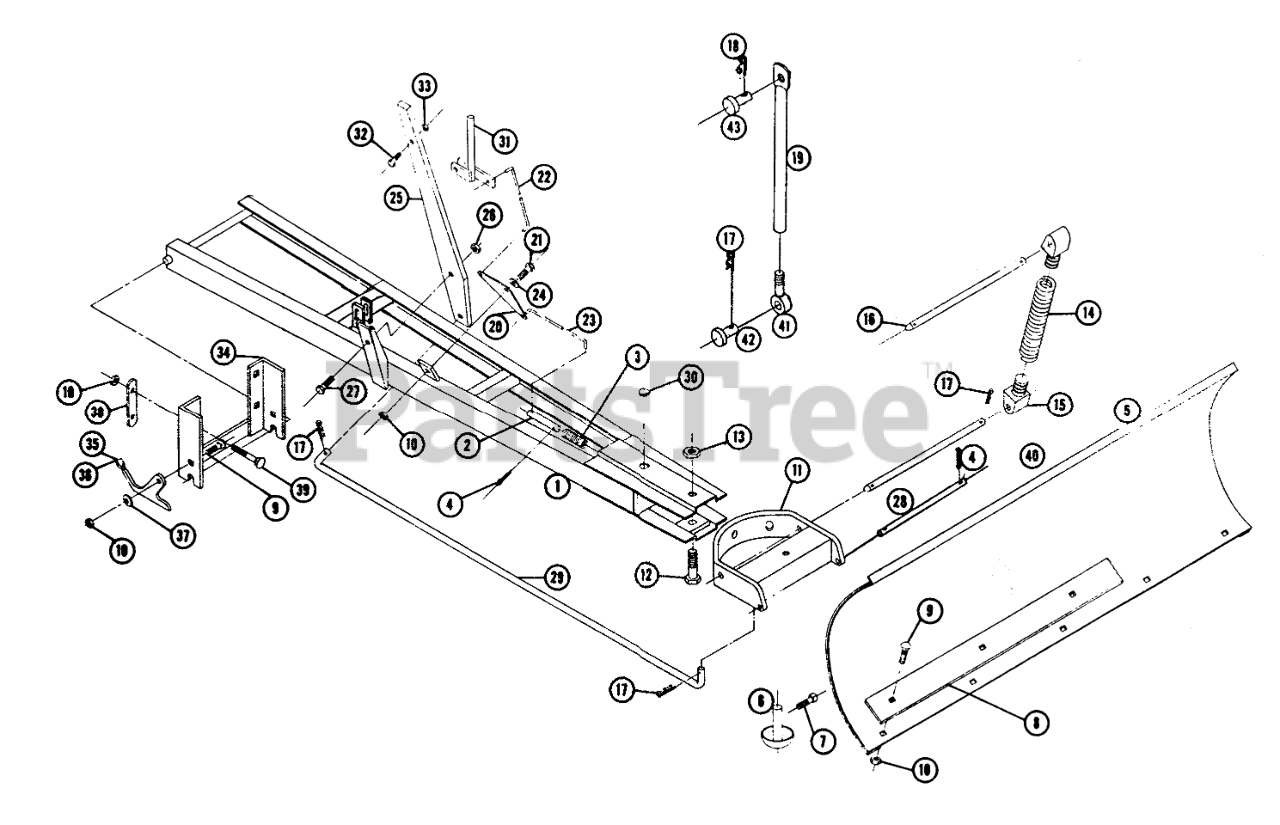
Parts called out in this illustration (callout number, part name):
1	Ass-y-Frame
2	Index Pin
3	SPRING-COMPRESSION
4	Cotter Pin
5	Ass-y-Blade
6	Skid
7	Set Screw 3/8-16 x 5/8 Sq. HD.
8	Plate-Blade Edge
9	Bolt 3/8-16 x 1
11	Sector and Channel
12	Bolt-Hex 3/4-16 x 3 3/4
13	Nut-Hex 3/4-16 Elastic Stop
14	Spring
15	Lug
16	ROD-PIVOT, BLADE
17	Hairpin
18	Hair Pin
19	Rod-Lift
20	Index Plate
21	Bolt-Hex 3/8-16 x 1
22	Rod-Upper Index
23	Head-Cylinder
24	Washer
25	Lever
26	Nut-1/2-13
27	Bolt Hex 1/2-13 x 1
28	ROD-LOWER
29	Rod-Blade Control
30	PLUG
31	INDEX LEVER
32	Bolt-Hex 1/4-20 x 1
33	Nut-Nylok
34	Ass-y Bracket-Mtg.
35	Plate-Latching R.H.
36	Plate-Latching L.H.
37	Washer-Spring
38	BRACKET-REAR LINK MOUNTING
39	Bolt-Carriage 3/8-16 x 3 1/4
40	Decal
41	Rod End
